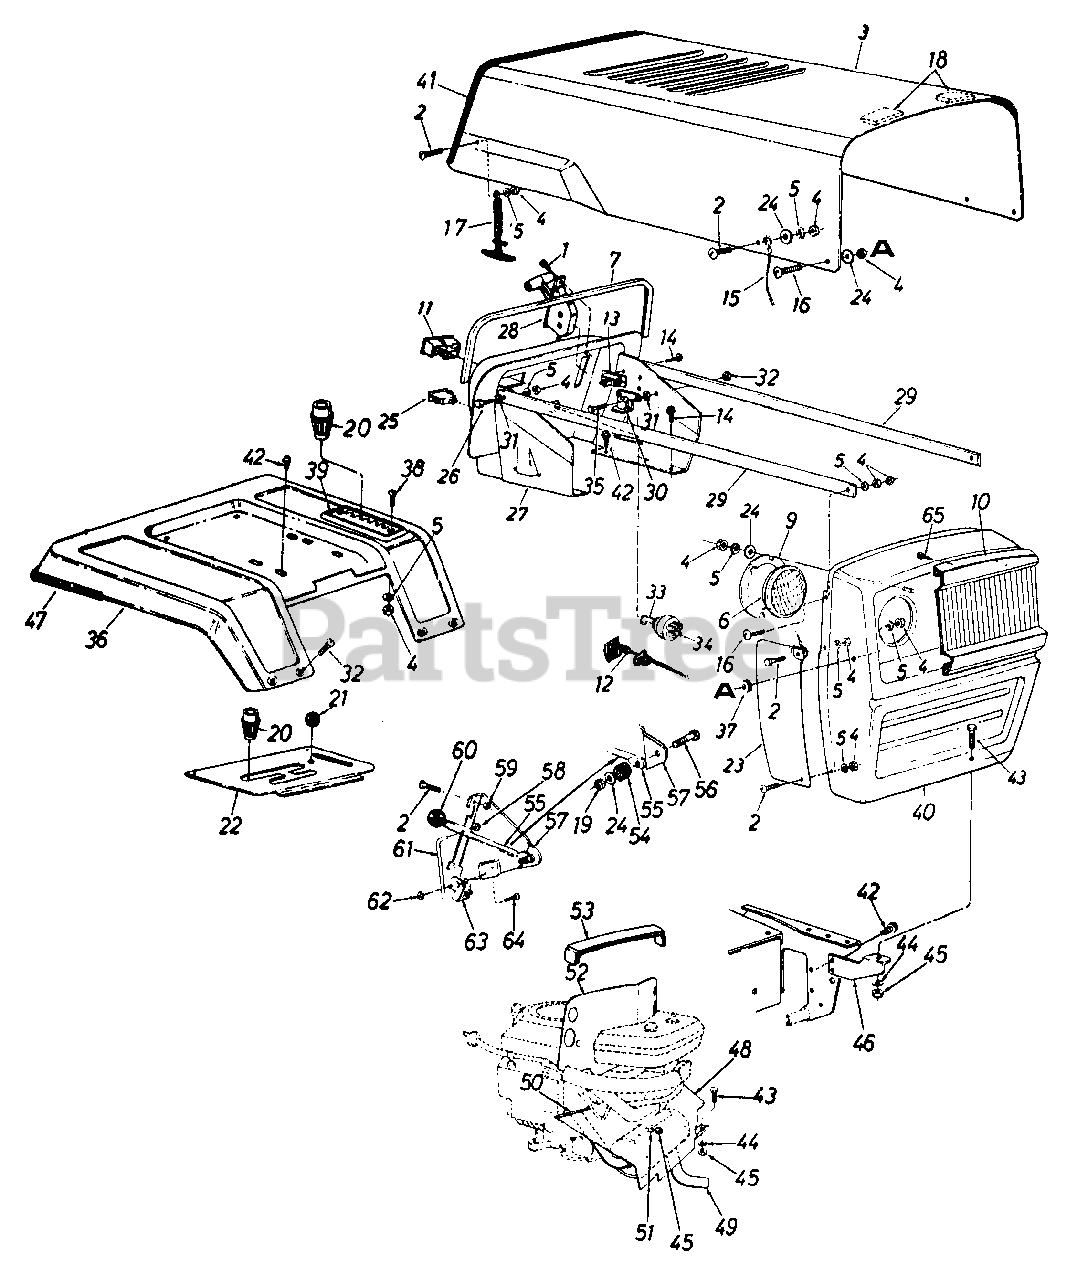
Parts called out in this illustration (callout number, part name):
1	Truss Mach. AB-Tap Scr. #10 x .5" Lg.
2	Truss Mach. Scr. 1/4-20 x .5"
5	L-Wash. 1/4" I.D."
6	Headlight
7	Trim Strip 29" Lg.
9	Headlight Retainer
10	Bezel
11	Ammeter
12	Choke Control 46" Lg.
13	Circuit Breaker 8 Amp
14	Hex Tap Scr. #10 x .5" Lg.
15	Hood Stop
16	Truss Mach. Scr. 1/4-20 x .75"
17	Hood Latch Ass'y.
18	Foam Strip
19	Hex Patch L-Nut 1/4-20 Thd.
20	Shift Knob
21	Ball Knob Brake
22	Transmission Cover
23	Grille Side Panel-R.H.
24	Fl-Wash. .281" I.D. x .73" O.D.
25	Light Switch
26	Truss Mach. Scr. 1/4-20 Thd.
27	Dash Panel Ass'y.
28	Throttle Control Box Ass'y.
29	Grille Support Rod
30	Solenoid
31	Ext. L-Wash. 1/4" I.D.
32	Carriage Bolt 1/4-20 x .5" Lg.
33	Ignition Key
34	Ignition Switch
35	Hex Bolt 1/4-20 x .5" Lg.
36	Rear Fender
37	Rubber Washer
38	Truss Mach. Scr. 1/4-20 x .62"
39	7-Speed Index Brkt.
40	Grille Ass'y.
41	Trim Strip 30" Lg.
42	Hex Wash. AB-Tap Scr. 5/16 x .75" Lg.
43	Hex Bolt 5/16-18 x .75" Lg.
44	L-Wash. 5/16" I.D.
45	Hex Nut 5/16-18 Thd.
46	Grille Mtg. Bracket-R.H.
47	Trim Strip 81" Lg.
48	Front Heat Shield
49	Muffler
50	Trim Strip 10" Lg.
51	Spec. L-Wash. 5/16" I.D.
52	Top Heat Shield
53	PVC Foam
54	Rubber Washer
55	PTO Lever
56	Hex Bolt 1/4-20 x 1.25" Lg.
57	Deck Clutch Control Brkt.
58	Push Cap
59	Hex Sems Nut 1/4-20 Thd.
60	Knob-Blade Clutch
61	Deck Control Rod
62	Hex Nut #10-24 Thd.
63	Safety Switch
64	Truss Mach. Scr. #10-24 x .5"
65	Self-Tap Scr. #8 x .5"
